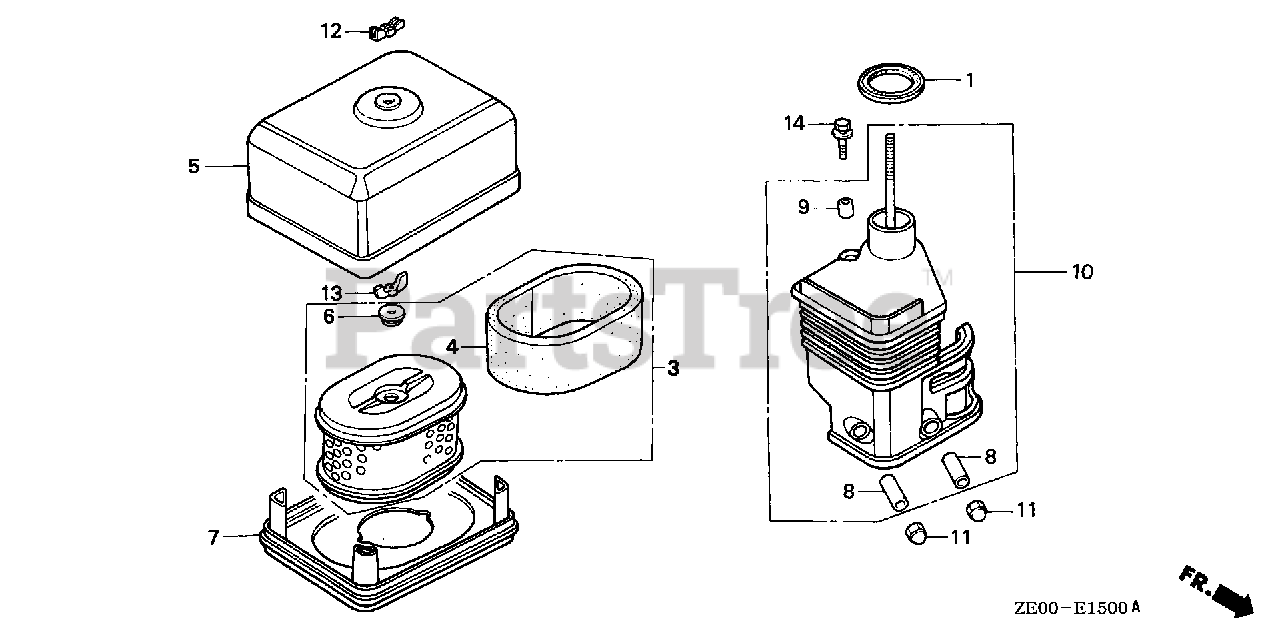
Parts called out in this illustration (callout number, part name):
1	GASKET, ELBOW
3	ELEMENT, AIR CLEANER (DUAL)
4	FILTER (OUTER)
5	COVER, AIR CLEANER (DUAL)
6	GROMMET, AIR CLEANER
8	COLLAR, AIR CLEANER (NOT AVAILABLE)
8	COLLAR, AIR CLEANER
9	COLLAR B, AIR CLEANER
10	ELBOW, AIR CLEANER
11	NUT, CAP (6MM)
12	NUT, AIR CLEANER COVER (DACRO COATING)
13	NUT, TOOL BOX SETTING
14	BOLT-WASHER (6X20)
